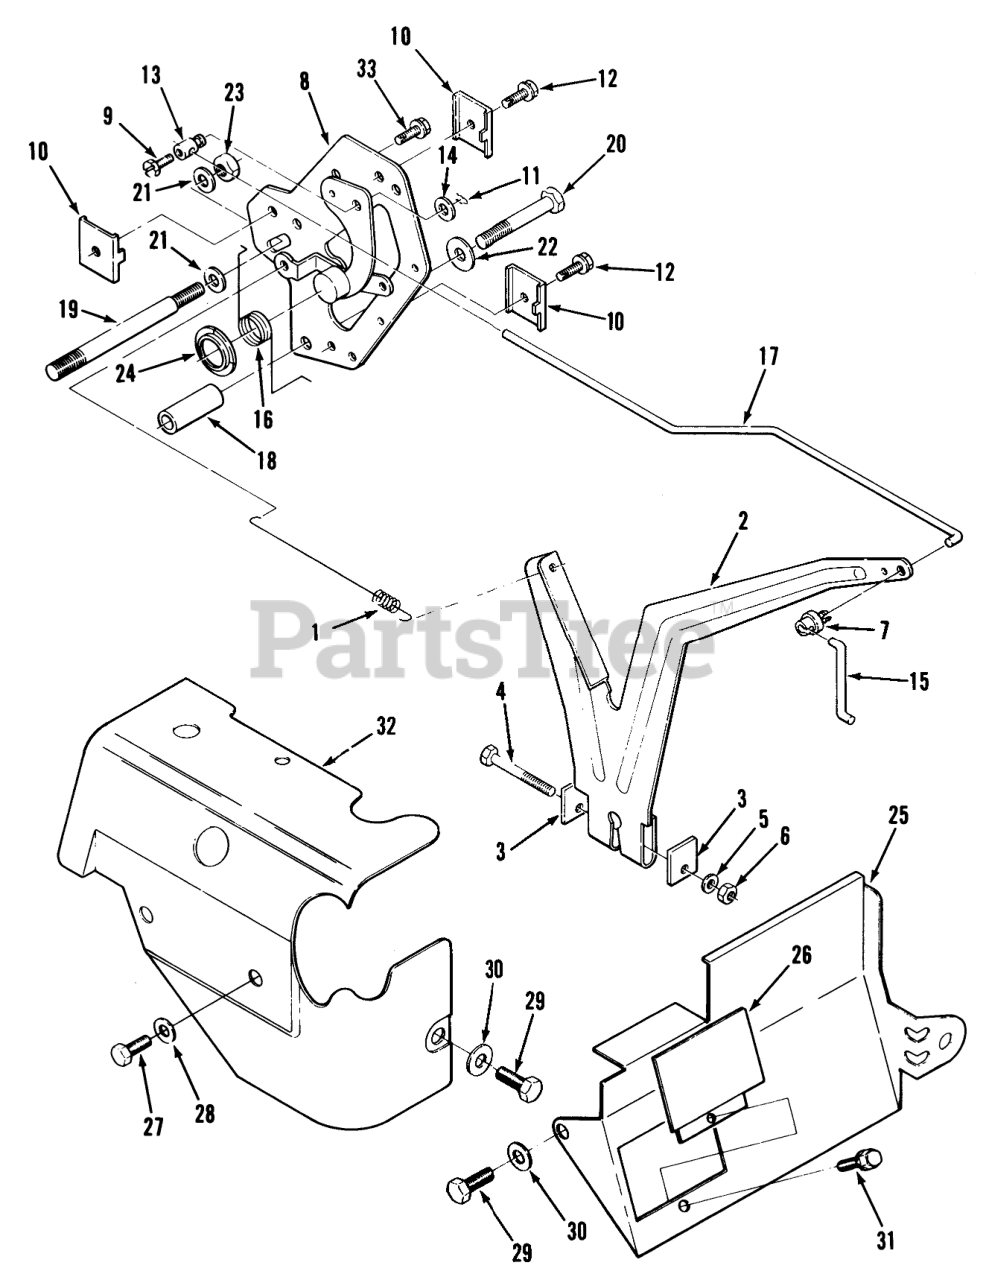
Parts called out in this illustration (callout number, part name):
1	SPRING-GOVERNOR
2	LEVER-GOVERNOR
3	WASHER
4	HHCS-M8 X 35MM
5	WASHER
6	Nut
7	Clip
8	Throttle Plate Assembly (Includes Control & Choke Levers, Pivot Pin, and Flat Washers)
9	HHMS #8-32X3/8"
10	CLAMP-CONTROL
11	Cotler Pin
12	Bolt
13	SWIVEL-CHOKE LEVER
14	Washer
15	LINK-THROTTLE
16	SPRING-CHOKE LINKAGE
17	LINK-CHOKE
18	SPACER
20	SCREW
21	Washer
22	Nut-M8
23	NUT-HEX M6
24	RING-RETAINER
25	DEFLECTOR-AIR
26	CVR-VOLT REGULATOR
27	HHCS-M8 X 10MM
28	Washer
29	HHCS-M8 X 10MM
30	Nut-M8
31	Bolt
32	Housing
33	STFHWH 12-24 X 1"
